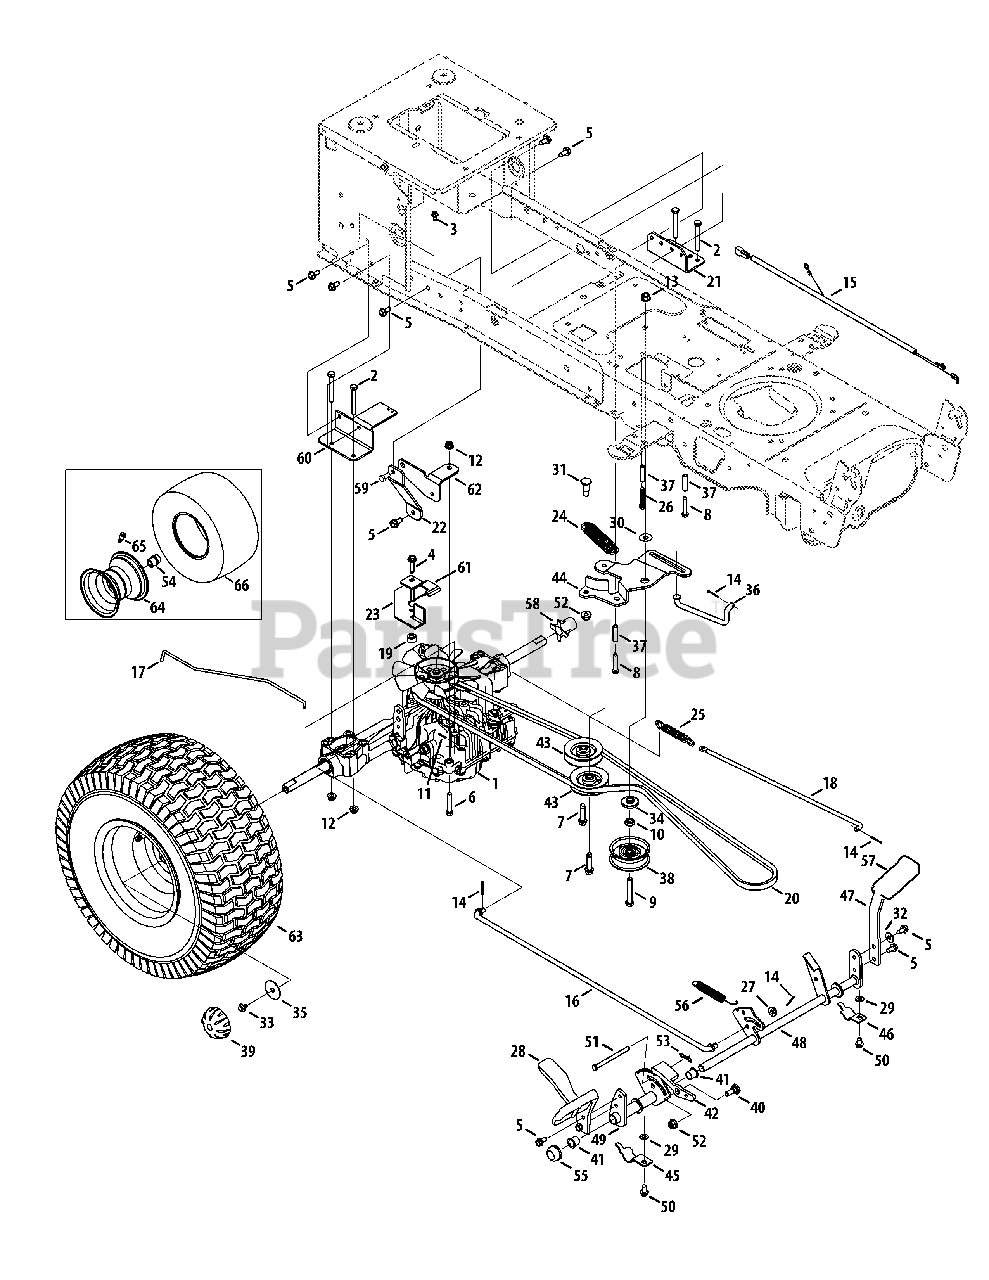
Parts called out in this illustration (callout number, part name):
1	Transmission, Tuff Torq K46
2	Hex Screw, 5/16-18, 2.50, Gr5, Std
3	Screw, Self-tapping, 1/4-20, 0.500
4	Screw, Self-tapping, 5/16-18, 1.250
5	Screw, Self-tapping, 5/16-18, .750
6	Hex Screw, 5/16-18, 1.75, Gr5
7	Screw, Self-tapping, 3/8-16, 1.500
8	Screw, Self-tapping, 1/4-20, 1.625
9	Hex Screw, 3/8-16, 2.25, Gr5
10	Nut, Jam, 7/16-20, Gr2
11	Pin, Cotter, 3/32, 1.0
12	Nut, Flange Lock, 5/16-18, Nylon
13	Nut, Flange Lock, 3/8-16
14	Pin, Cotter, 3/32, 1.0
15	Jumper Harness, Ground & Reverse
16	Rod, Control, Tuff-Torq
17	Rod, Hydro Bypass
18	Rod, Brake, NX9 Tuff-Torq
19	Spacer, .330 x .715 x .430
20	Belt, V-Type
21	Bracket, Mount, Tuff-Torq
22	Bracket, NX9 Tuff Torq
23	Bracket, Belt Keeper
24	Spring, Extension, 1.00 Dia x 4.75
25	Spring, Extension, .59 Od x 4.00
26	Screw, Self-tapping, 1/4-20 x 1.75
27	Washer, Flat, .375 x .738 x .063
28	Control Pedal
29	Washer, Flat, .344 x .688 x .065
30	Wash, Flat, .385 x 1.00 x .030
31	Scr, Shldr, .50 x .685 3/8-16
32	Washer, Bell, .340 x .872 x .060
33	Screw, 5/16-24 x .750
34	Spacer, Shoulder, 1.375 x .380 x .183
35	Washer, Flat, .350 x 1.59 x .062
36	Rod, Transmission, Bypass
37	Spacer, .260 x .372 x 1.420
38	Pulley, Idler, Flat 2.75 OD
39	Cap, Hub
40	Bolt, Shoulder, .500 x .270, 3/8-16
41	Bearing, Flange, .630 x .695 x .60
42	Latch, Cruise
43	Pulley, Idler, V-Type x 3.06
44	Bracket, Idler, Center Double
45	Bracket, Support, Pedal Strap
46	Bracket, Support, Pedal Strap 5/8
47	Bracket, Pedal, Brake
48	Control Assembly, Brake
49	Bracket Assembly, Pedal, Hydro
50	Screw, Self-tapping, 5/16-18, 0.625,
51	Pin, Clevis, 5/16 x 3.985
52	Nut, Flange Lock, 3/8-16, Nylon
53	Pin, Cotter, Bow-Tie 72
54	Axle Hub
55	Cap, Push 5/8
56	Spring, Extension, .63 Dia x 4.95
57	Pad, Pedal, Brake
58	Sleeve, .765 Id x 1.500
59	Hex Cap Screw, 3/8-16 x .75
60	Bracket, Mount
61	Bracket, Belt
62	Bracket, Support
63	Wheel Assembly
64	Rim Assembly, Bead
65	Tubeless Air Valve
66	Tire, 20 x 8 x 8
